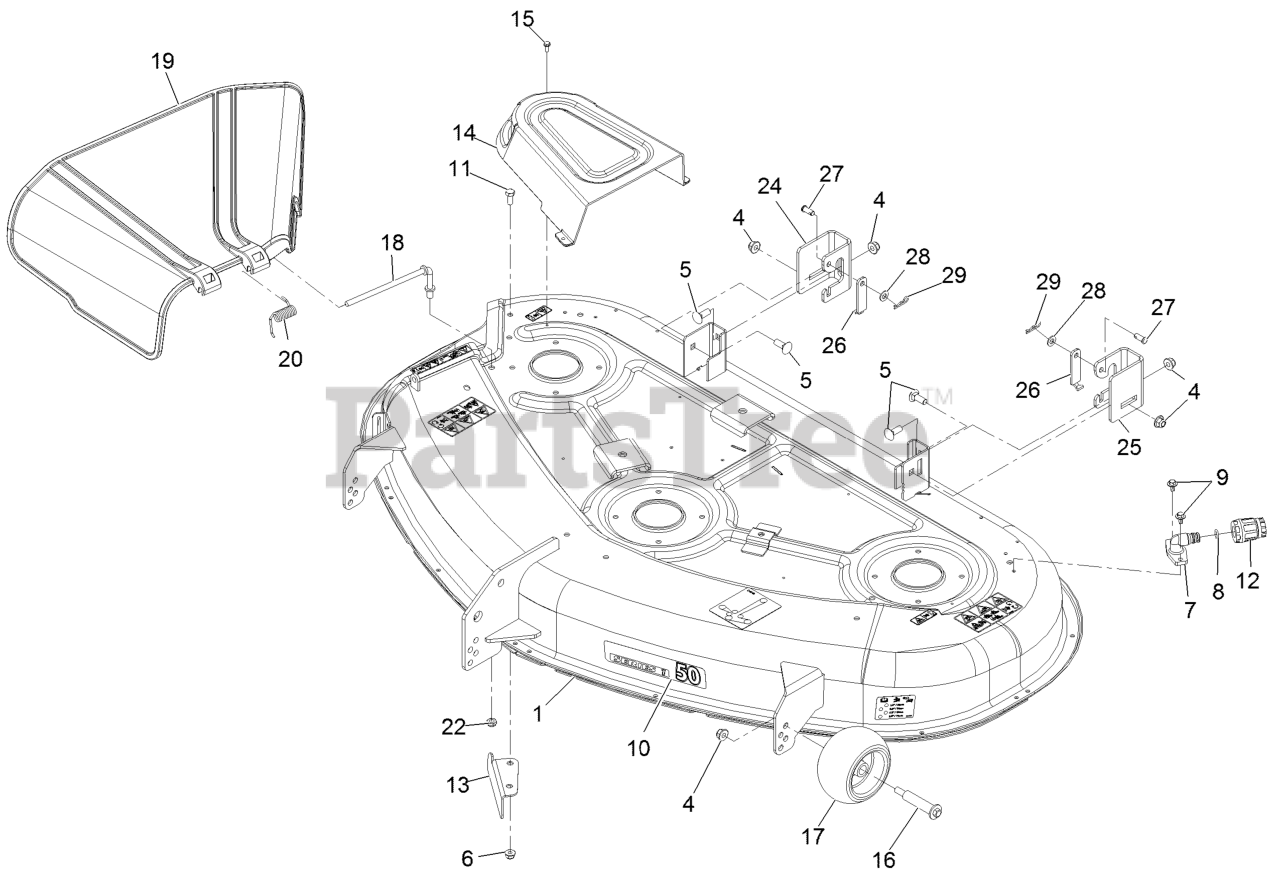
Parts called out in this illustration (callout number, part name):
1	50 INCH DECK AND DECAL AS
4	NUT-HF, NI
5	BOLT-CARR
6	NUT-HF, NI
9	SCREW-HHFTF
10	DECAL-SERIES 1 - 50
11	SCREW-HH
12	CONNECTOR-HOSE
13	BAFFLE-CUTOFF
14	COVER-BELT
15	SCREW-TAPTITE
16	BOLT-SHOULDER
17	ROLLER-SCALP, ANTI
18	ROD-PIVOT
19	DEFLECTOR
20	SPRING-TORSION
24	BRACKET - HANGER, RR
25	BRACKET - HANGER, LR
26	LINK - DECK RETENTION
27	PIN-CLEVIS
28	WASHER-PLAIN
29	PIN-COTTER
